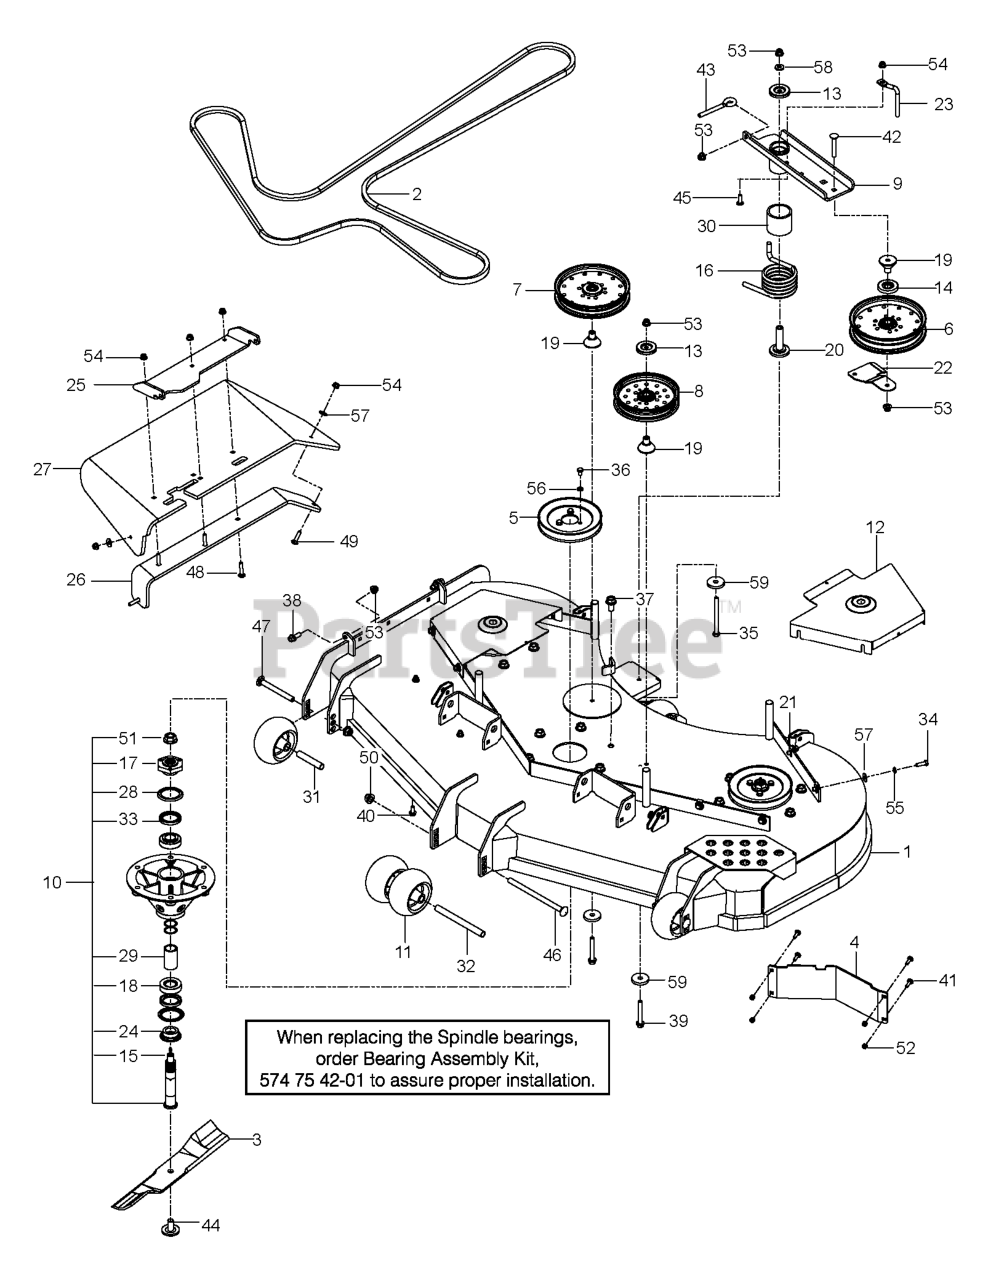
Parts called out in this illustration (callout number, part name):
1	DECK.SVC.W/DECALS.PZ.54"
2	BELT.5V.169.75
3	BLADE, 19"
4	BAFFLE, DIVERTER 54"/60" LH
5	PULLEY - 6.57
6	PULLEY - IDLER 7"
7	PULLEY - 7" NARROW
8	PULLEY IDLER, 6" NARROW
9	ASSY, IDLER ARM, PZ
10	RP_SPINDLE.ASM.10".IRON.1/8-27
11	ROLLER, GAUGE .635 BORN
12	SHIELD,BELT, 60" ORANGE
13	DUST SHIELD
14	SHIELD, DUST
15	ZERK
16	SPRING, TORSION, IDLER
18	BEARING
19	BEARING, IDLER ARM
20	BEARING, IDLER PIVOT
21	U-CLIP 5/16-18 NUT RETAINER
22	BELT.GUIDE.BLACK
23	BELT KEEPER
25	BRKT - CHUTE MTG BLACK
26	BRKT, CHUTE SUPPORT BLACK
27	CHUTE, DISCHARGE 48-52
28	SEAL V-RING 55MM
30	SPACER, IDLER PIVOT
31	TUBE, ROLLER AXLE
32	TUBE, ROLLER AXLE LONG
33	SEAL SHAFT
34	HCS 5/16C X 1
35	HCS 3/8-16 X 4-1/2 GR 8 ZD
36	HCS 5/16-18 X 1/2 GR 5 ZD
37	HHFS 1/2-13 X 1 GR5 ZD
38	HHFS 3/8-16 X 1 GRD 5 ZD
39	HHFS 3/8-16 X 2 3/4
40	HHFS 5/16-18 X 3/4
41	1/4-20X3/4 CARR BLT
42	CARRIAGE BOLT 3/8-16 X
43	EYE BOLT, 3/8 X 4"
44	BLADE BOLT/WASHER
45	RHSSNB 5/16C X 1.0
46	RHSNB 1/2-13 X 8 GR5 ZD
47	RHSNB 1/2-13 X 4.75 GR5 ZD
48	RHSNB 5/16-18 X 1-1/2 GR 5 ZD
49	BOLT, CARRIAGE 5/16X1-1/4
50	NUT, 1/2-13 HEX FLG NYLOC ZD
51	NUT FLANGE 3/4-16
52	NUT.1/4-20.HEX.NYLOC.ZD
53	NUT 3/8-16 HEX FLG NYLOC ZD
54	5/16-18 NYLOC FLANGE NUT
55	WASH.5/16.SLW.ZD
56	WASH 5/16 DISC SPRING ZD
57	WASHER 5/16 FLAT
58	WASHER, 3/8 THICK
59	SPINDLE WASHER
